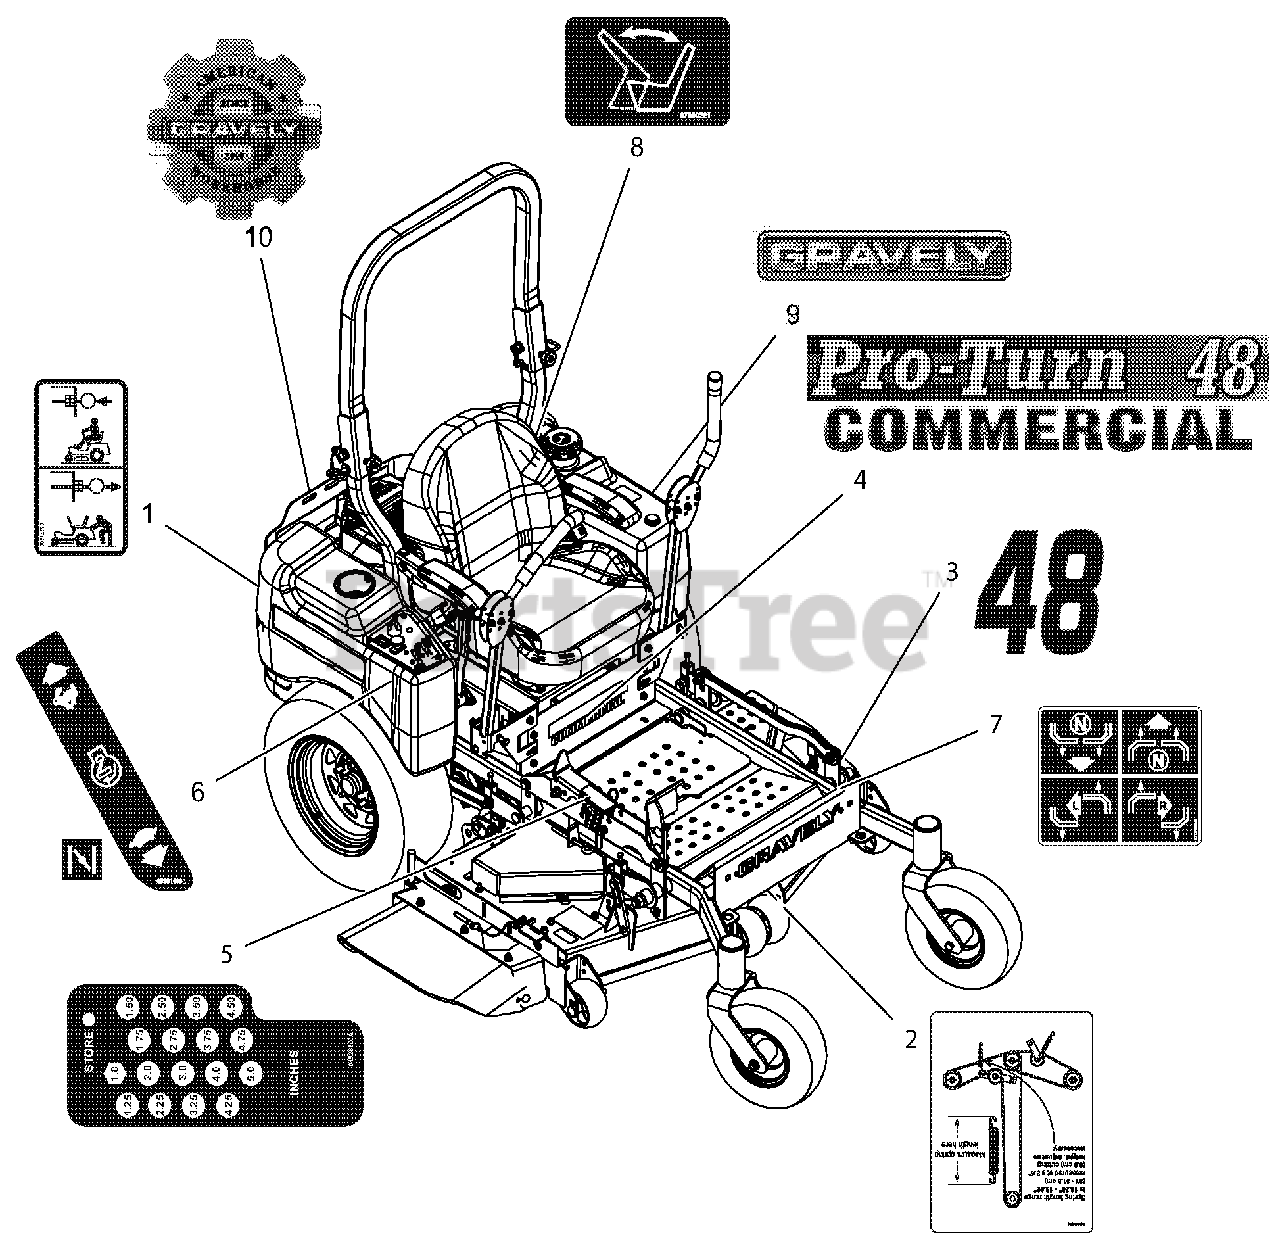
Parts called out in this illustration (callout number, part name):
1	DECAL, TRANSMISSION DISCONNECT
2	DECAL, BELT ROUTING
3	DECAL, 48"
4	DECAL, 48" PRO-TURN
5	DECAL, HEIGHT OF CUT
6	DECAL, SPEED CONTROL
7	DECAL, INSTRUCTIONAL - STEERING
8	DECAL, SEAT RELEASE
9	DECAL, FUEL TANK-GRAVELY
10	DECAL, GRAVELY HERITAGE-LARGE
